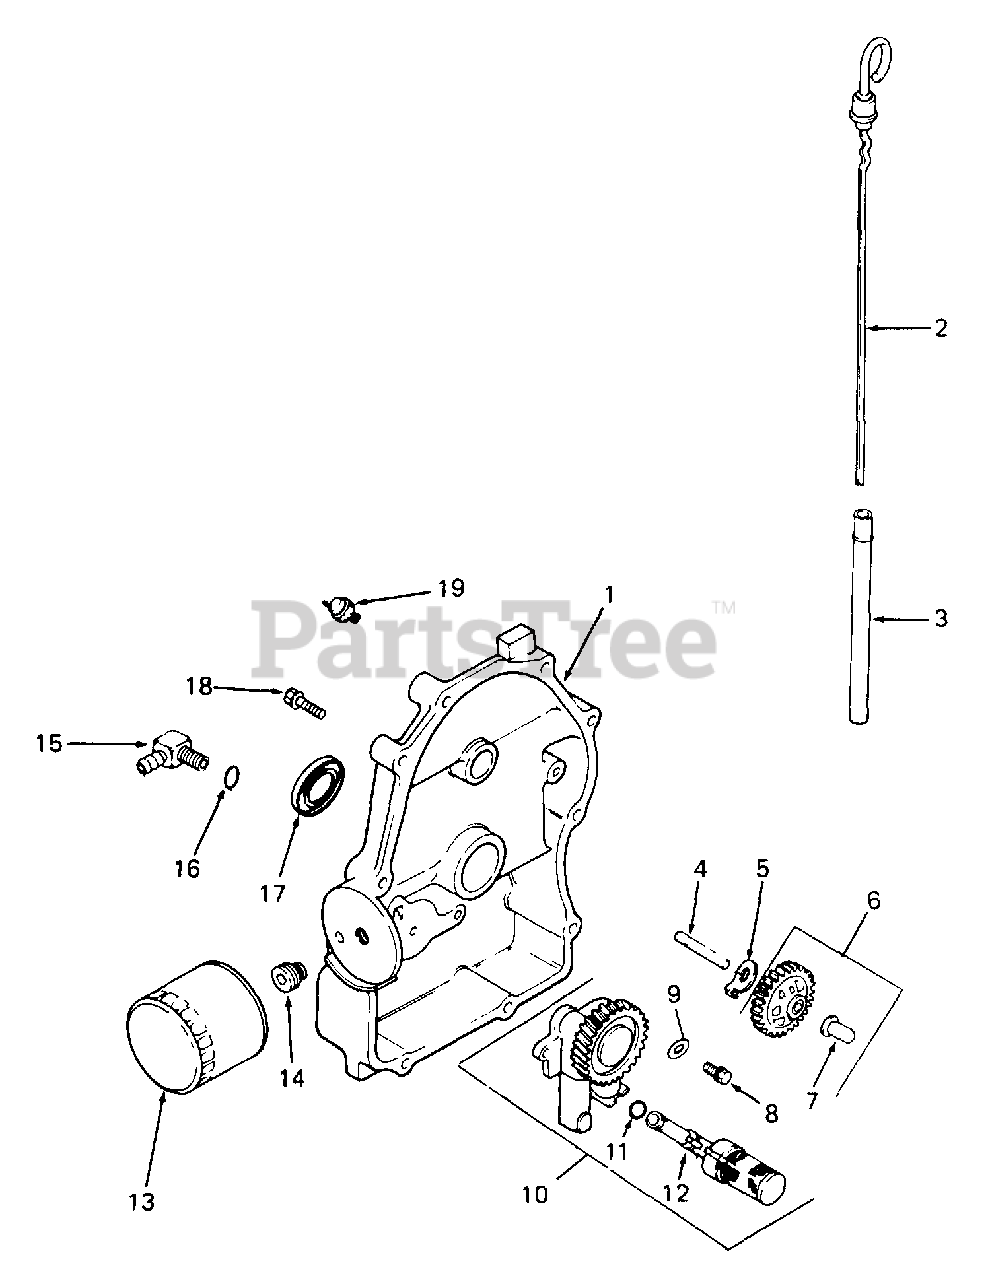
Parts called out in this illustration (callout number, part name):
1	Plate, Closure
2	Dipstick
3	Tube, Dipstick
4	Shaft, Governor Gear
5	Tab, Locking
6	Kit, Governor Gear w/Pin
7	Pin, Governor Regulating
8	Screw, M6 x 1.0 x 25
9	Washer, Plain
10	Oil Pump Assembly
11	O-Ring, Oil Pick-Up
12	Pick-Up, Oil
13	Filter, Oil
14	Nipple, Oil Filter
15	Connector, 90ø Hose
16	O-Ring, Oil Passage
17	Seal, Oil
18	Screw, Closure Plate, M8 x 1.25 x 45
19	Switch, Oil Pressure
